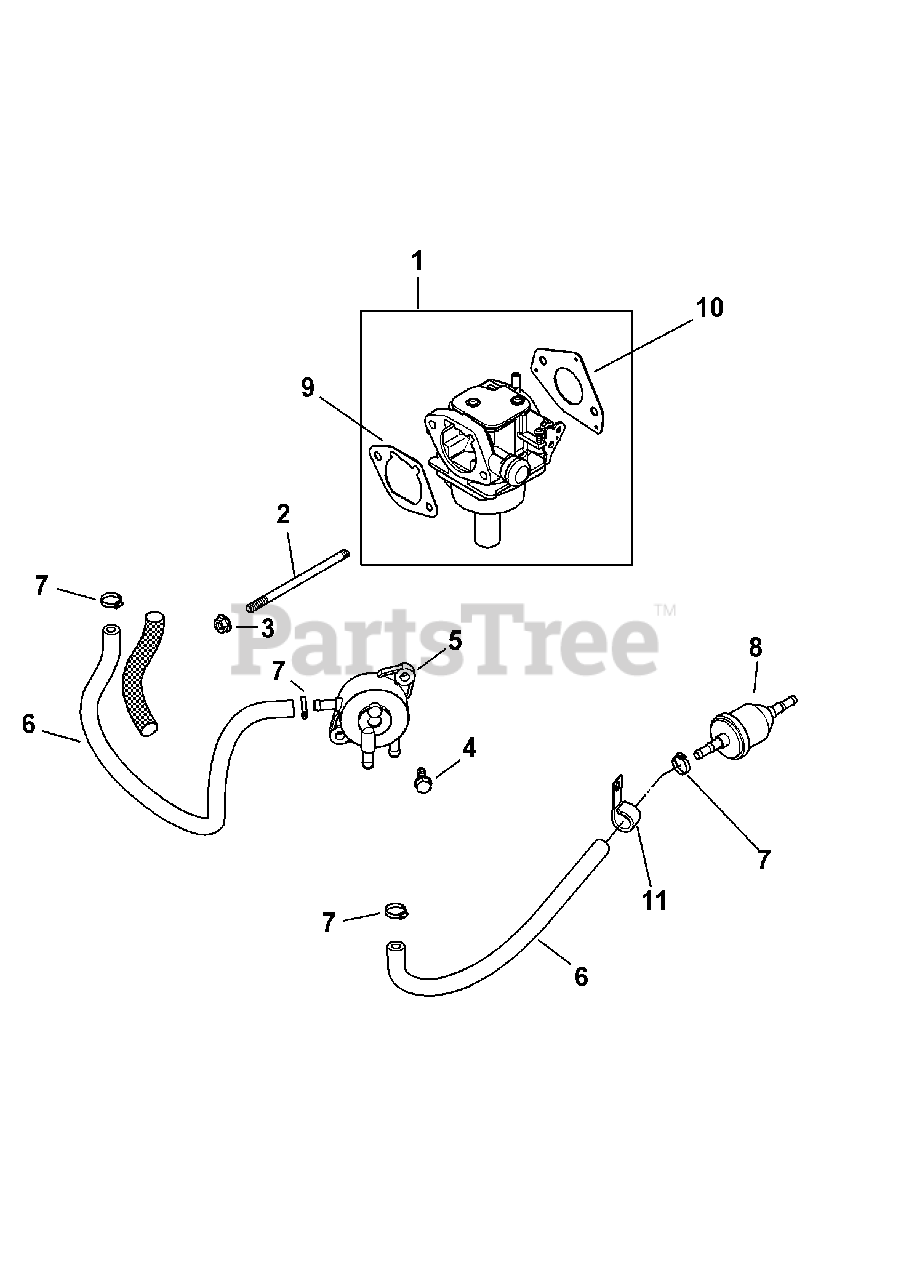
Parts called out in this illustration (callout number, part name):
1	Carburetor Kit
2	Stud, M6 x 1.0 x 106
3	Flange Nut, M6 x 1.0
4	Tap Screw, M6 x 1.7 x 18
7	Hose Clamp, 1/2
9	Air Cleaner Base Gasket
10	Carburetor Gasket
